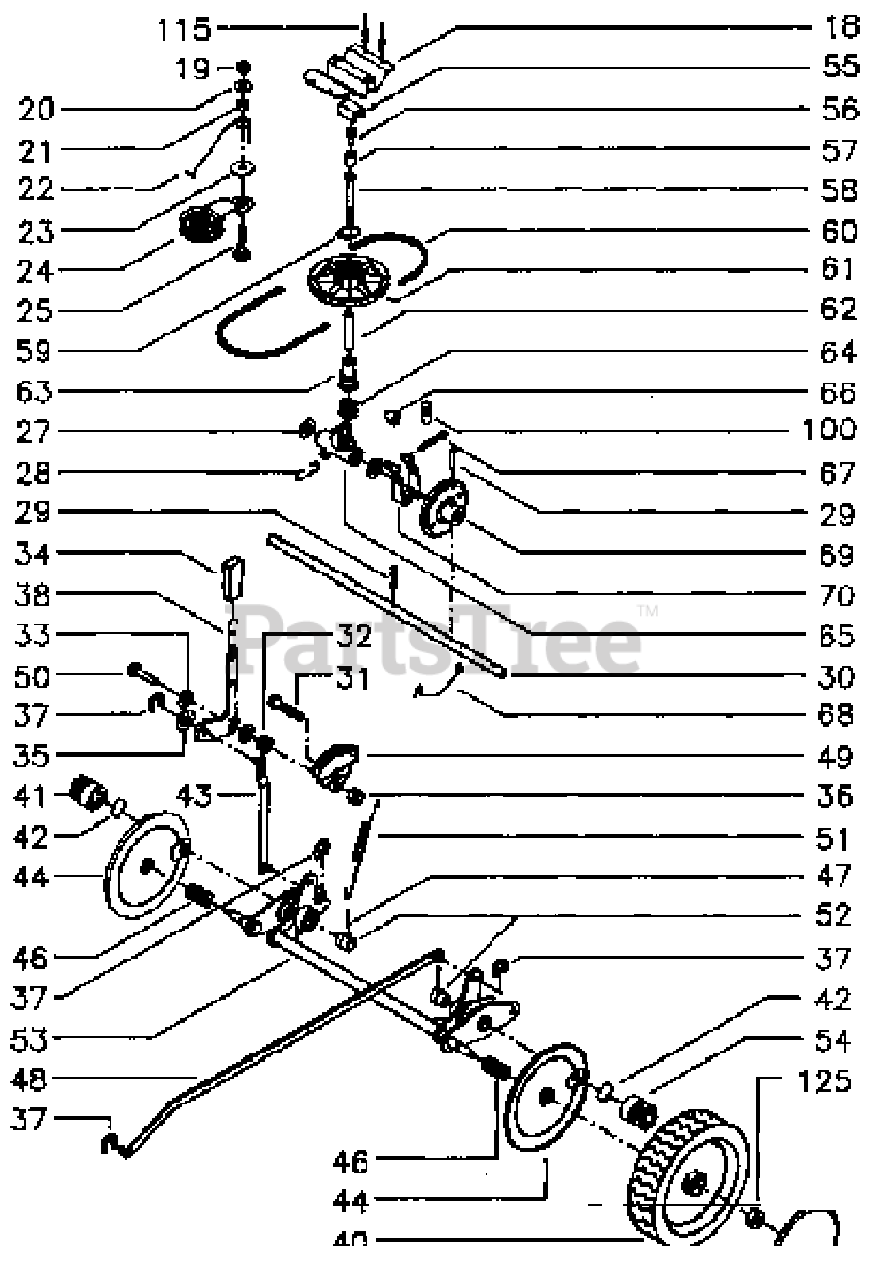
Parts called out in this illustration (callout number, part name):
19	Locknut M6
24	Tensioner
27	Washer
28	Clips
29	Spring Pin 5x28
30	Shaft
31	Screw
39	Wheel Cover
41	Pinion, Right
42	Carrier
44	Shield
46	Spring
49	Indexplate
54	Pinion, Left
55	Slide Bearing
56	Screw
60	Belt
61	Pulley
63	Sleeve
65	Holder
68	Holder Spacer
69	Wheel Assy Friction
70	Ram
